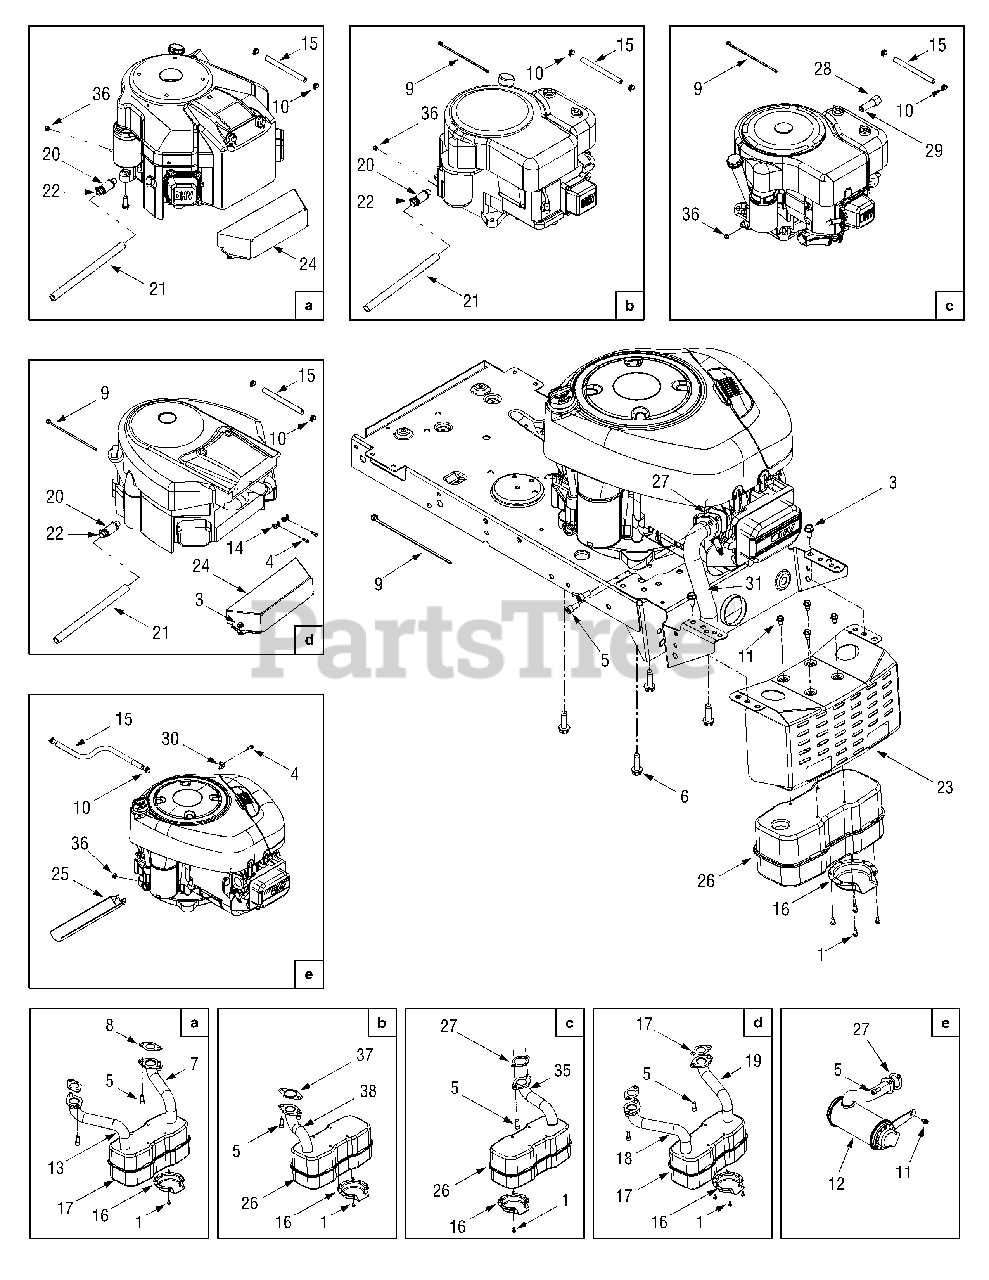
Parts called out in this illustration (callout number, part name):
1	Screw, #8-18, .500
2	Self-tapping Screw, 1/4-14, .625
3	Self-tapping Screw, 5/16-12, .75
4	Screw, #10-32, .625
5	Socket Cap Screw, 5/16-18, .625
6	Self-tapping Screw, 3/8-16, 1.25
7	LH Exhaust Pipe
8	Exhaust Gasket
9	Cable Tie, 7.4"
10	Hose Clamp, .490
11	Screw, 1/4-20, 0.500
12	Muffler, Exhaust
13	RH Exhaust Pipe
14	Casing Clamp
15	Fuel Line Hose
16	Muffler Deflector
17	Muffler, Twin Inlet
18	RH Exhaust Pipe
19	LH Exhaust Pipe
20	Oil Drain Valve
21	Oil Drain Hose
22	Oil Drain Cap
24	Engine Heat Shield
25	Oil Drain Sleeve
26	Muffer, Single Inlet
27	Exhaust Gasket
28	Oil Drain Cap, 3/8-18
29	Oil Drain Pipe, 3/8-16, 2.0
30	Casing Clamp
31	Exhaust Pipe
32	Screw, #8-18 x .50
33	Hex Screw, 7/16-20, 1.25
34	Belt Keeper Pin, 5/16, 4.75
35	Exhaust Pipe
36	Hex Sems Nut, 1/4-20
37	Exhaust Gasket
38	Exhaust Pipe
